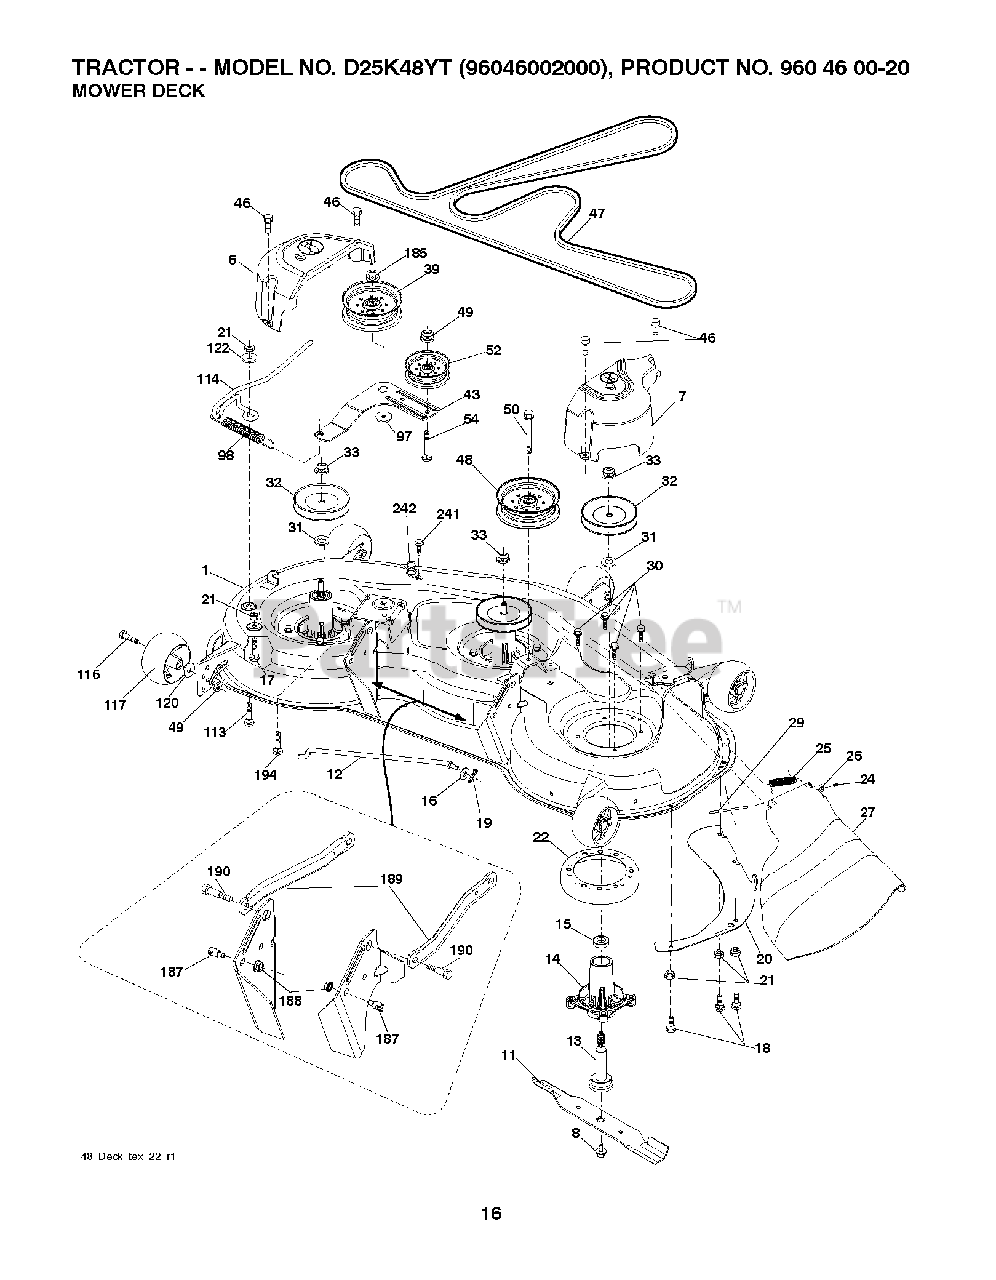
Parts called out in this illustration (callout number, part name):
1	DECK.WELDMENT.48".4GWB.BLUE
6	COVER.MANDREL.LH.48"
7	COVER.MANDREL.RH.48"
8	BOLT.WASHER.ASM.7/16-2
11	48" HI-LIFT BLADE
11	BLADE.MULCH.48"
12	ROD.ANTI.SWAY.48/54"K4
13	SHAFT ASM MANDREL
14	HOUSING.MANDREL.4PT.
15	BEARING
16	WASHER
17	BOLT
18	BOLT
19	PIN.COTTER.5/16.BOW TI
20	BAFFLE, VORTEX MWR
21	LOCKNUT
22	STRIPPER.MANDREL.ROUND.BLACK
24	CAP-SLEEVE LT
25	SPRING, TORSION
26	NUT PUSH M
27	Deflector Assembly, 48" Black
29	ROD.HINGE
30	SCREW, WASHER HEAD
31	WASHER.SPACER.MANDREL
32	PULLEY MANDREL
33	NUT.FLANGE.LOCK.TOP
39	PULLEY.IDLER.4.50/HUB SPECIAL
43	ARM.IDLER
46	SCREW.1/4-20X5/8
47	BELT.DRIVE.DECK
48	PULLEY.IDLER.2006
49	NUT LOCK FLG 3/8-16 UNC
50	SCREW TT 3/8-16X2-1/4 UNC
52	PULLEY.IDLER.48"PRIMARY
54	BOLT.3/8-16X1.50
98	SPRING, DECK DRIVE
113	BOLT CRT
114	ROD.TENSION.RELIEF.TEX (2 2)
116	BOLT.SHOULDER.3/8-16X3-5/8.
117	WHEEL. GUAGE RALLY
120	WASHER
122	BUSHING.RELIEF.TENSION
185	NUT.LOCK.FLANGE.7/16
187	STUD.FASTNER.W/ANTI-ROTATE
188	NUT LOCK HEX FLANGE 5/16-18
189	ARM.SUSPENSION.MOWER
190	BOLT.SHOULDER
194	BOLT.CARR.SQNK.7/16
241	SCREW.TT.#10-32X.5.3/8.FLANGE
242	PORT.WASHOUT
